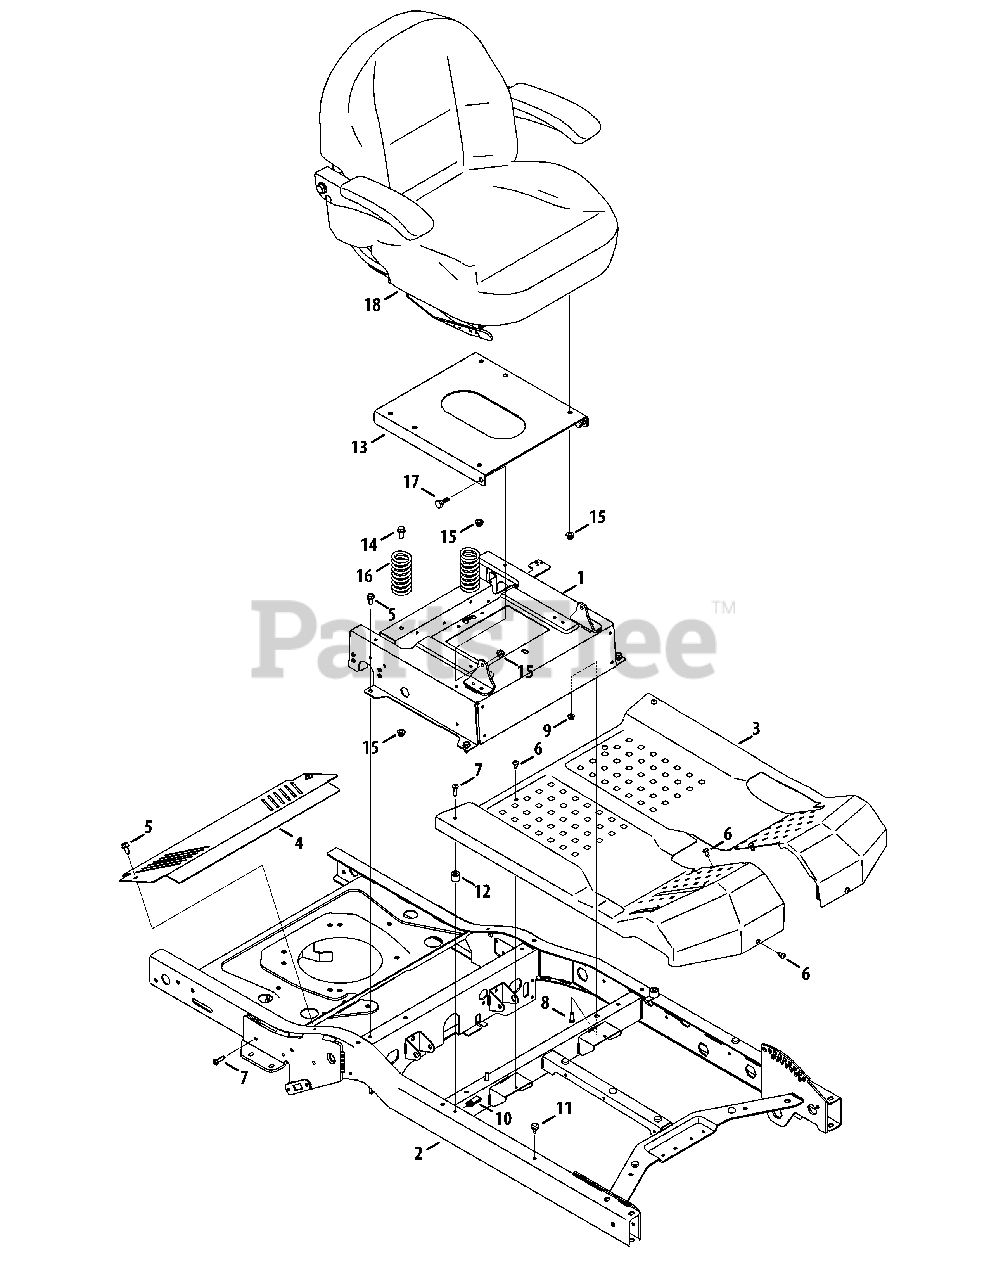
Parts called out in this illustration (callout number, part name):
1	Seat Mount Frame
2	Frame Assembly
4	Transmission Cover
5	Hex Washer Screw, 5/16-18 x .750
6	Screw, 1/4-20 x .5
7	Screw, 1/4-20 x 1.0
8	Hex Screw, 1/4-20 x .75
9	Flange Lock Nut, 1/4-20
10	Speed Nut, 1/4-20, U-Type
11	Bumper, .62 x .22
12	Spacer, .281 x .750 x .680
13	Seat Base
14	Hex Washer Screw, 5/16-18
15	Flange Lock Nut, 5/16-18
16	Comp. Spring, 1.71 x 3.735 x .238
17	Shoulder Screw, 5/16-18 x .437 x .268
18	Seat w/ Arms
